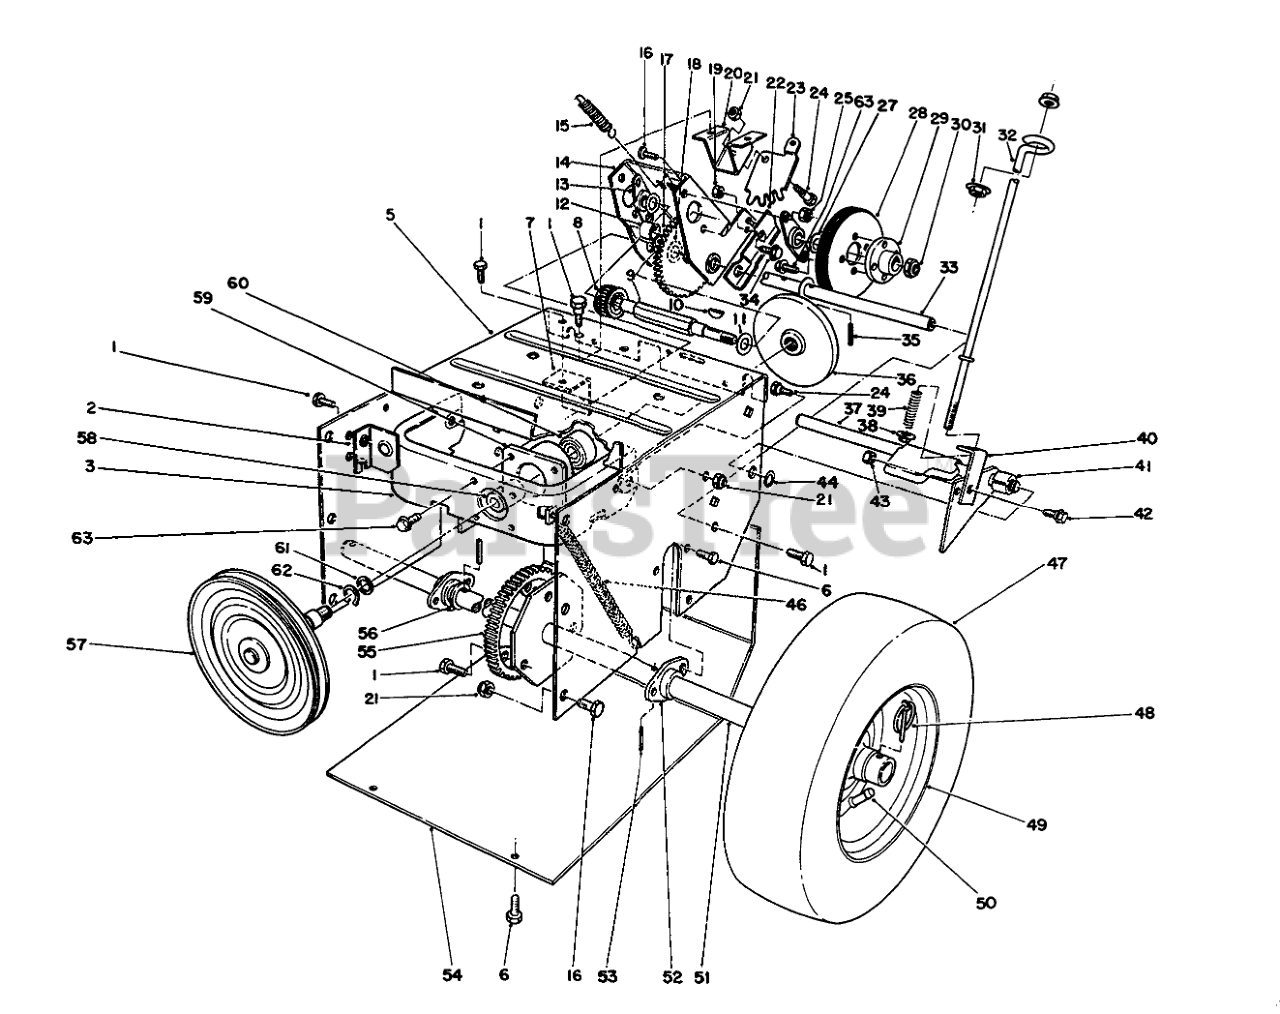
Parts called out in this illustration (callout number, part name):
1	SCREW-HWHTF
2	BRACKET-MOUNT, FRONT
3	Frame-Friction Plate
5	Frame-Traction
6	SCREW-HWH
7	BRACKET-MOUNT, REAR
8	PINION
9	SHAFT-WHEEL, FRICTION
10	KEY-WOODRUFF
11	WASHER-FLAT
12	5/8ID X 1LG BUSHING
13	BEARING-WHEEL, FRICTION
14	BRACKET-SLIDING
15	SPRING-TRACTION
16	SCREW-HH
17	Intermediate Gear & Bushing (Incl. Ref. #12)
18	WASHER-SPECIAL
19	NUT-LOCK, NI
20	MOUNT-LEVER
21	NUT-LOCK, NI
22	CAM-RECEIVER
23	GEAR-QUADRANT
24	BOLT-SHOULDER
25	NUT-LOCK, NI
27	WASHER-THRUST
28	WHEEL-FRICTION
29	HUB-WHEEL, FRICTION
30	NUT-LOCK, NI
31	NUT-HF
32	ROD-TRACTION, LOWER
33	SHAFT-PIVOT
34	SCREW-HH
35	PIN-SPRING
36	PLATE-FRICTION
37	Traction Engagement Asm.
38	NUT-HHF
39	SPRING
40	BRACKET-TRACTION
41	SPACER
42	SCREW
43	NUT-LOCK, NI
44	RING-RETAINING
46	SPRING-PLATE, FRICTION
48	PIN-LYNCH
49	RIM-WHEEL
50	TUBE-INNER
51	SHAFT-AXLE
52	BEARING-AXLE
53	PIN-SPRING
54	Bottom Cover
55	GEAR-AXLE
56	WASHER-THRUST
57	PULLEY AND DRIVE ASM
58	BUSHING
59	HUB-FRAME, TRACTION
60	BEARING-BALL
61	WASHER-THRUST
62	RING-RETAINING, EXT
63	SCREW
